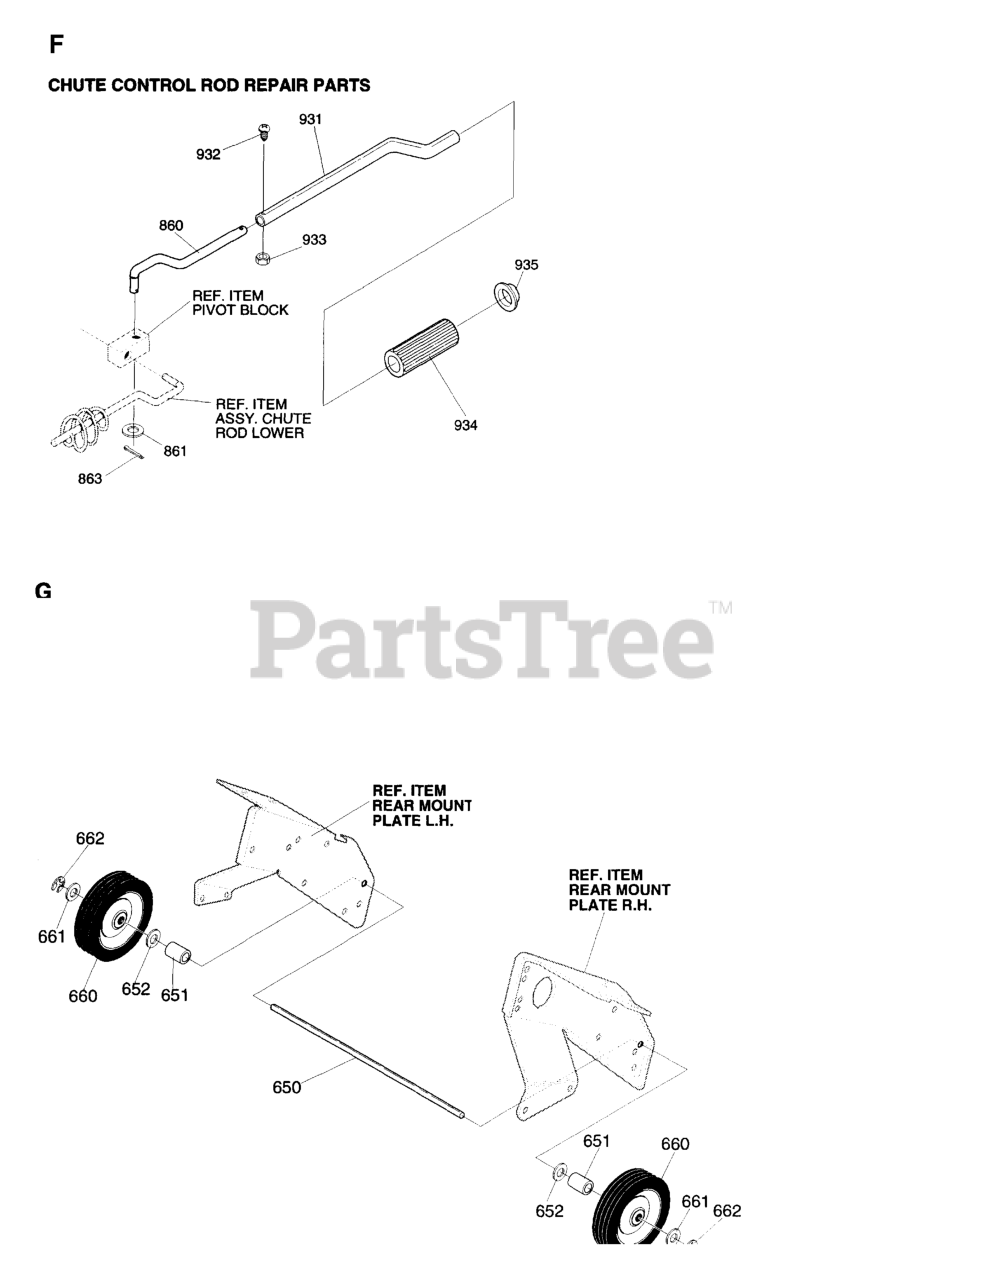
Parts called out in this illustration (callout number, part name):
590	PIPE LOWER
591	BOLT
602	BOLT.CARRIAGE.5/16-18
603	WASHER - 15X7.3X1.6
606	BOLT.FIN.HEX.5/16-18X3/4
607	WASHER - 15X7.3X1.6
608	LOCKNUT
611	Bolt - Rd. Hd. Sq. Neckiage 3/8 16 x 3/4
612	WASHER - 15X7.3X1.6
613	WASHER.LOCK.HVY.HLCL.SPR.5/16
621	Bolt - Rd. Hd. Sq. Neckiage 3/8 16 x 3/4
622	WASHER - 15X7.3X1.6
623	WASHER.LOCK.HVY.HLCL.SPR.5/16
625	BRACKET NLA
626	BOLT
627	NUT.CROWNLOCK.1/4
